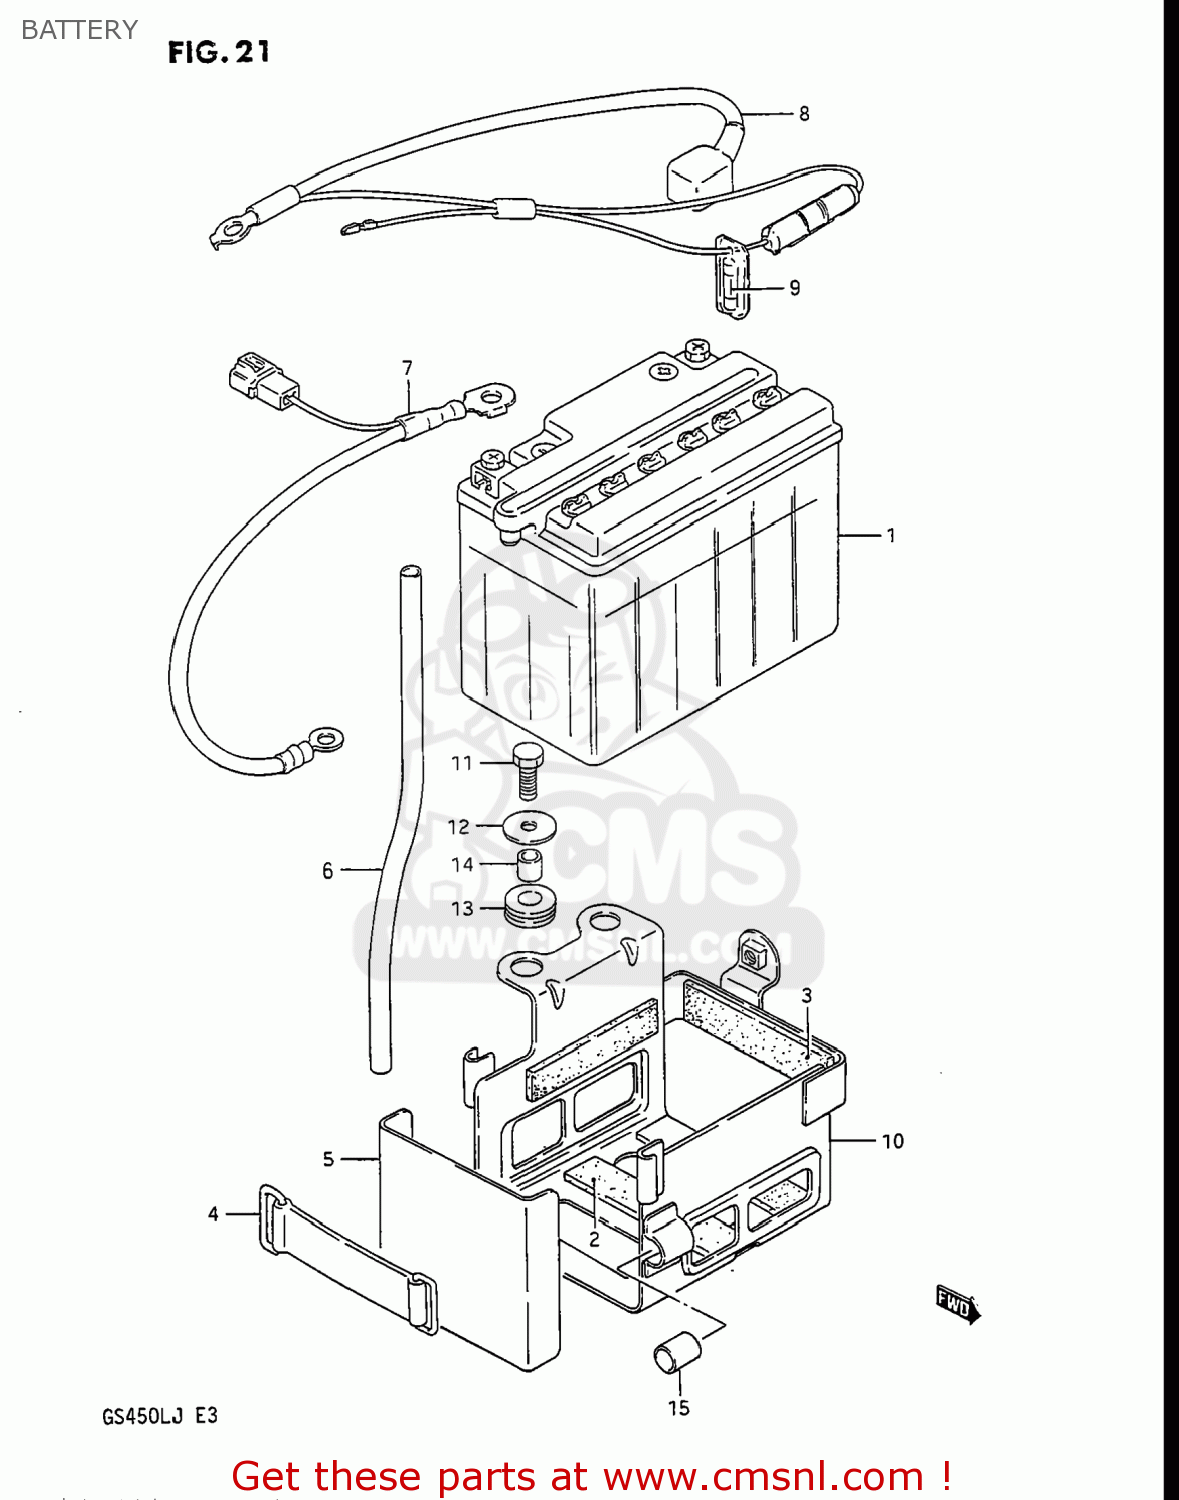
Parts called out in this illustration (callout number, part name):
1	BATTERY ASSEMBLY (12V)
2	PROTECTOR(170X95X3.0)
3	PROTECTOR,20X9
4	BAND
5	COVER,BATTERY
6	HOSE,BATTERY EXHAUST
7	WIRE,BATTERY MINUS
8	CASE ASSY,FUSE (WITH CABLE)
9	FUSE(15A)
10	HOLDER,BATTERY
11	BOLT,M6X1X20
12	WASHER
13	CUSHION
14	SPACER(6.2X9X7.5)
15	CUSHION
